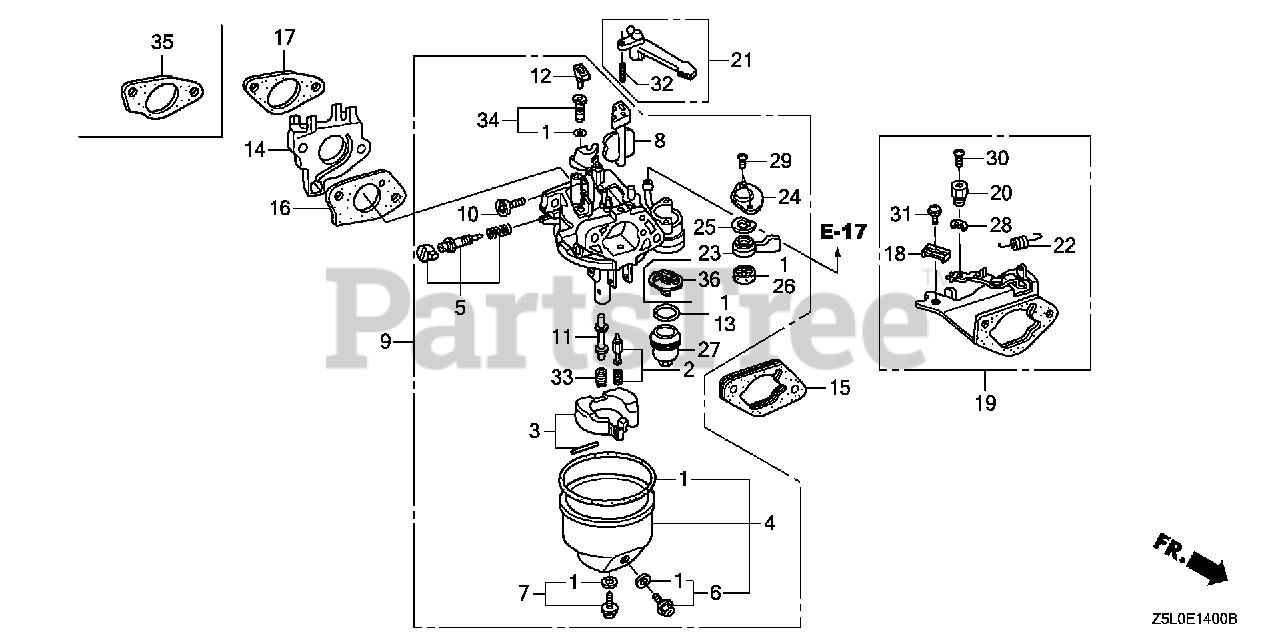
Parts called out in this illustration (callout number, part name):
1	GASKET SET (INCLUDES 16173-001-004)
2	VALVE SET, FLOAT
4	CHAMBER SET, FLOAT
5	SCREW SET, PILOT
6	SCREW SET, DRAIN
7	SCREW SET
9	CARBURETOR ASSY. (BE80D B/C)
10	SCREW, THROTTLE STOP
11	NOZZLE, MAIN
12	COLLAR, SETTING
13	GASKET, FUEL STRAINER CUP
14	INSULATOR, CARBURETOR
15	SPACER, CARBURETOR
16	GASKET, CARBURETOR
17	GASKET, INSULATOR
21	LEVER, CHOKE (STD)
23	LEVER, PETCOCK
24	PLATE, LEVER SETTING
25	SPRING, PETCOCK LEVER
26	GASKET, PETCOCK
27	CUP, FUEL STRAINER
29	SCREW, PAN (3X6)
32	PIN, SPRING (2X12)
33	JET, MAIN (#90)
33	JET, MAIN (#92)
33	JET, MAIN (#95)
34	JET SET, PILOT (#35)
